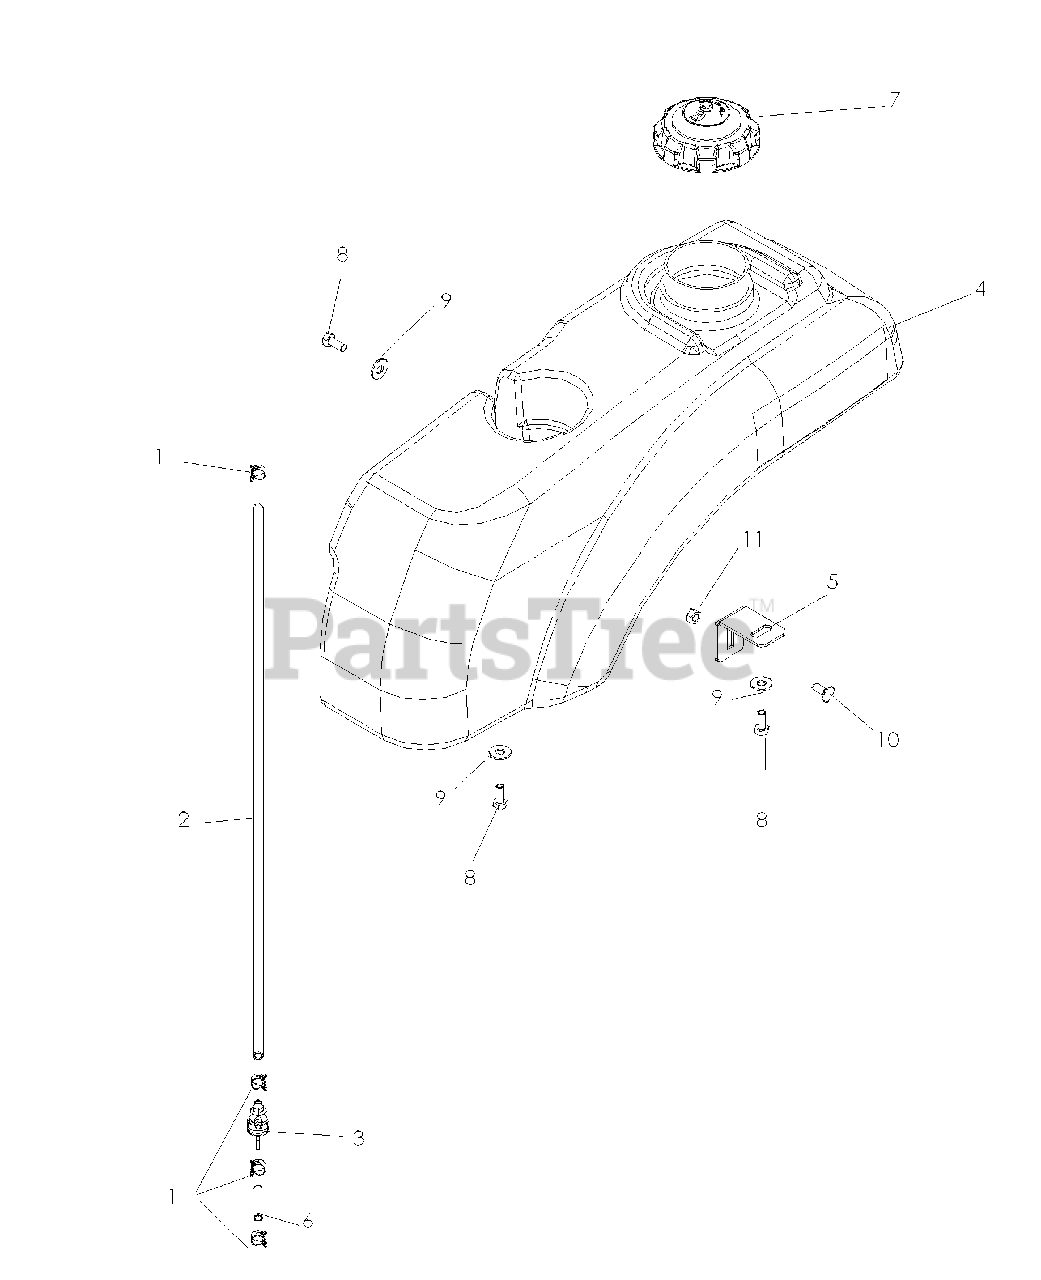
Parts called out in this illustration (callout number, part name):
1	HOSE CLAMP
2	HOSE 1/4 X 44
3	SHUT OFF VALVE
4	FUEL TANK ASM LH
5	TANK BRKT.
6	HOSE 1/4 X 2"
7	FUEL CAP ANTI-SPLASH
8	HCS 5/16C X 3/4
9	FLAT WASHER 5/16 SAE
10	BOLT 5/16C X 3/4" CARRIAGE
11	NUT 5/16 NYLOC
